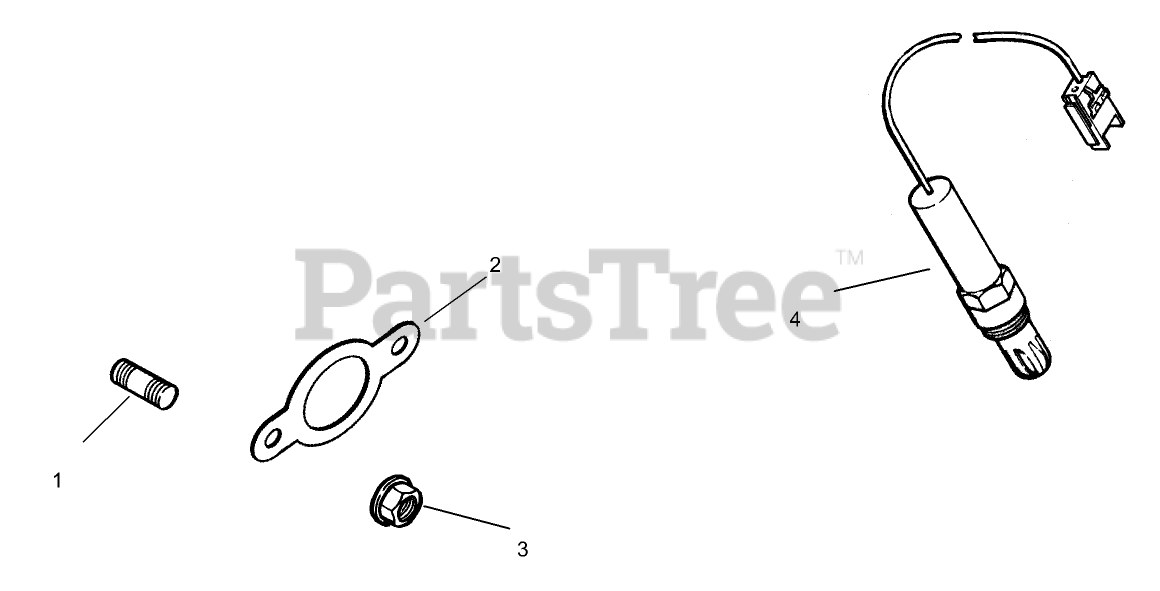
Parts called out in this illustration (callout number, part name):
1	STUD (M8X1.25X33)
2	GASKET-EXHAUST
3	NUT-FLANGE (M8X1.25)
4	Sensor-Oxygen
